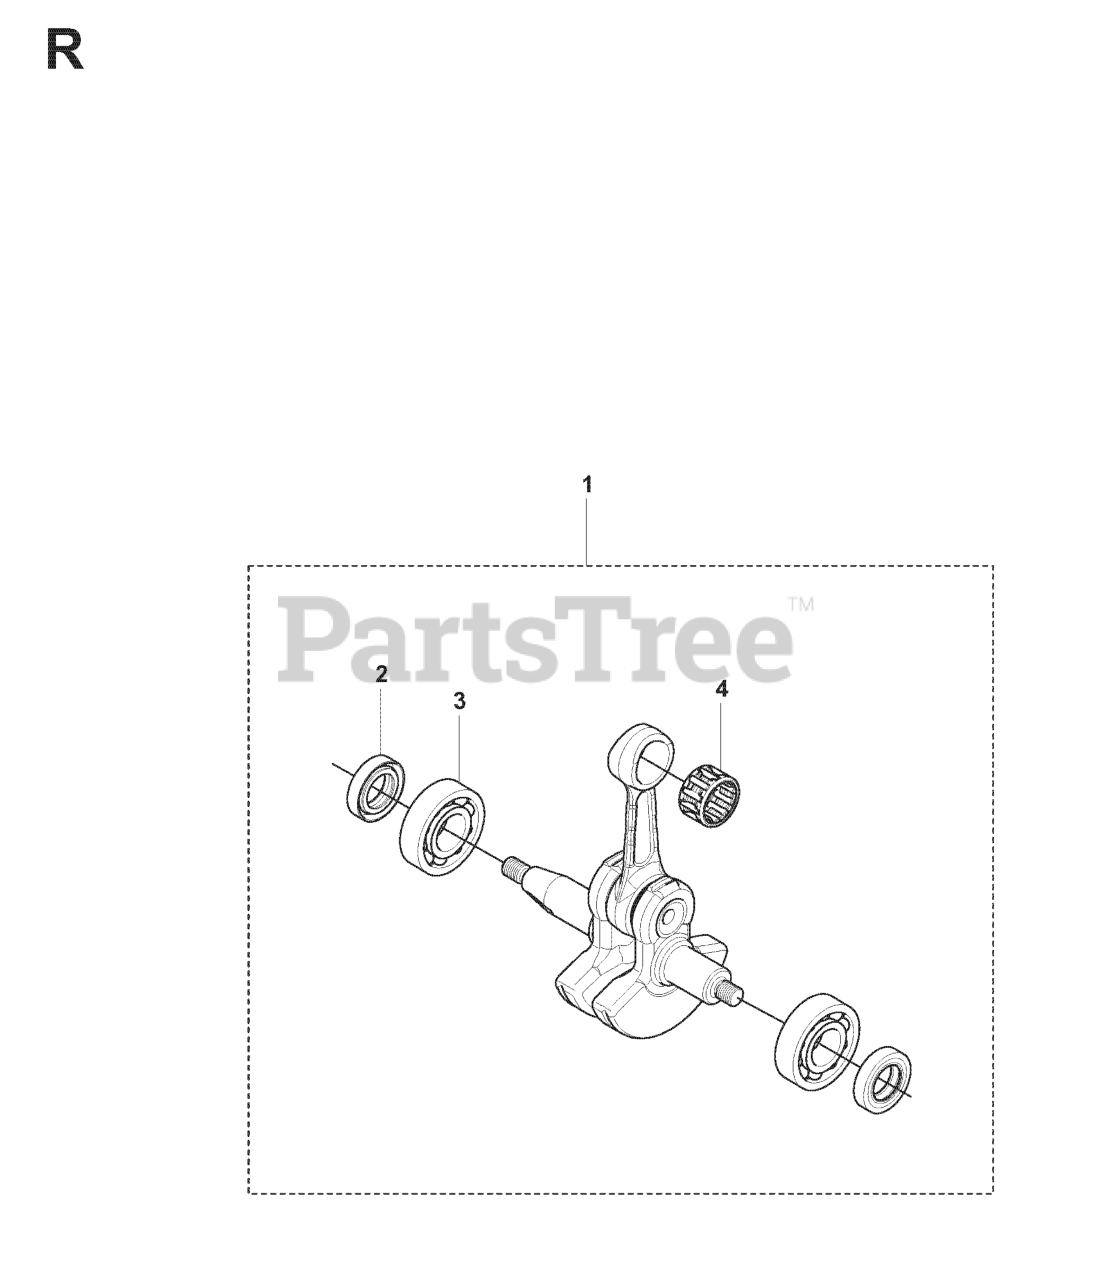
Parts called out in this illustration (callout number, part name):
2	SEALING RING
3	BALL BEARING
4	SUPPORT BUSHING
